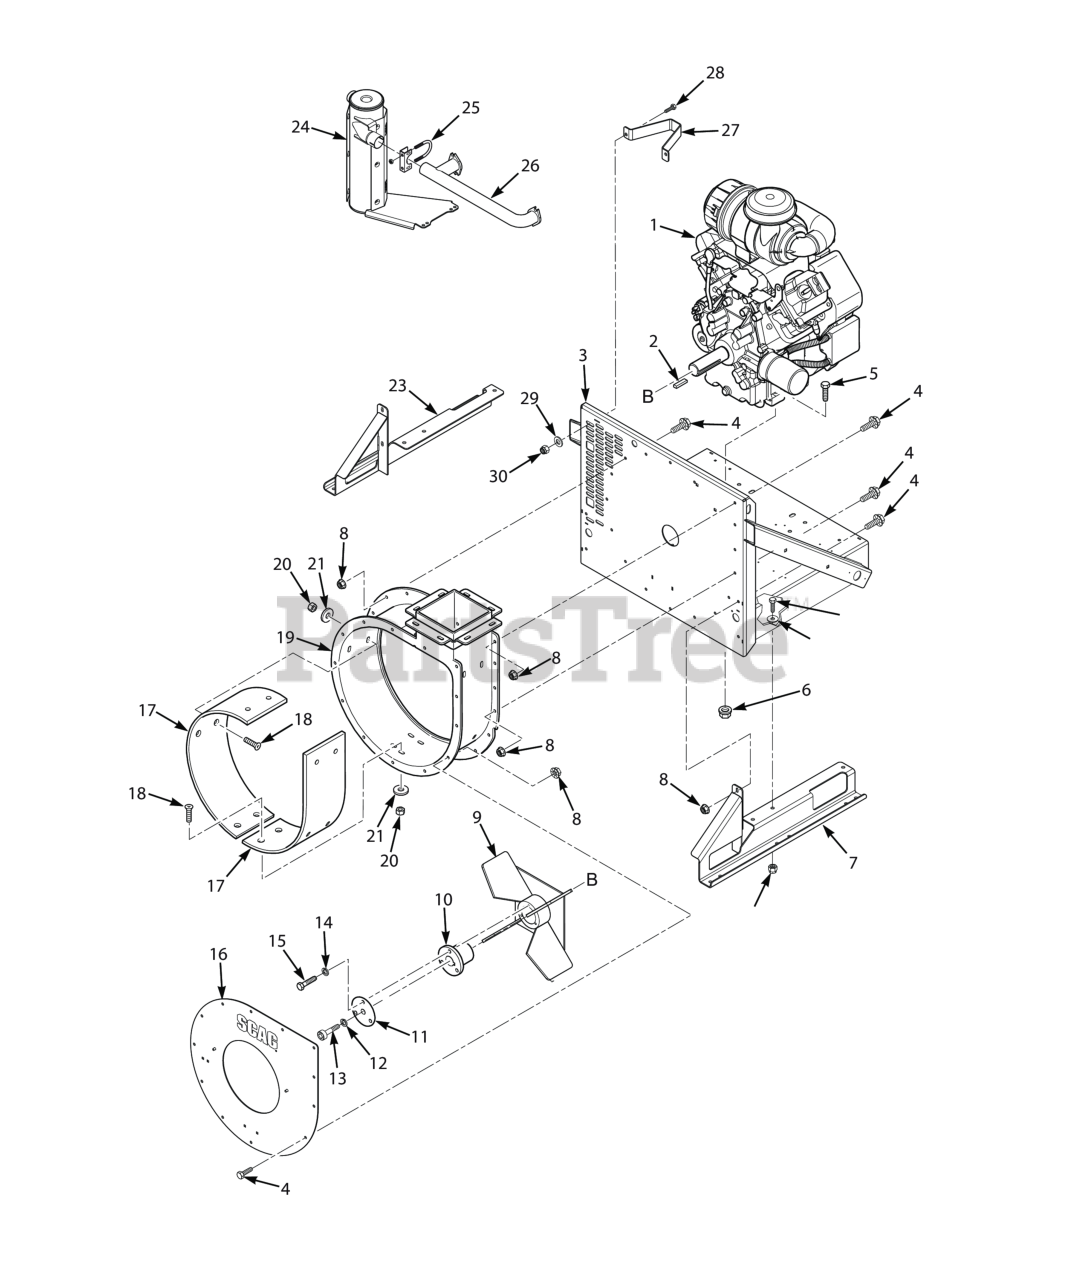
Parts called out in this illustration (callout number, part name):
1	Engine, 29HP Briggs & Stratton Vanguard
2	Key, 3/8 x 3/8 x 3-1/2"
3	Frame Weldment w / Decals
4	Bolt, Hex Head Serrated Flange 3/8-16 x 3/4"
5	Bolt, Hex Head 5/16-18 x 1-1/2" - Front
5	Bolt, Hex Head 5/16-18 x 2-1/2" (x3) (35BV & 37BV-EFI)
6	Nut, Serrated Flange 5/16-18 (Right Front Engine Mounting, Briggs and Kohler Only)
7	Mounting Bracket Weldment, RH Skid
8	NUT, 3/8-16 SERRATED FLANGE HEX HEAD
9	Impeller Weldment, TL20W
10	Hub, Tapered Locking Q2 x 1-7/16"
11	Cover Plate, Hub Taper - TL20W
12	Lockwasher, 5/8" Spring
13	Socket Head Cap Screw, 5/8-18 x 1-3/4"
14	Lockwasher, 3/8" Spring, Kawasaki FX / FS
15	Bolt, Hex Head 3/8-16 x 1-3/4" (Kohler EFI)
16	Cover, Housing - TLS20W w/Decal
17	Wearliner Kit w/ Hardware
18	Capscrew, 3/8-16 x 1-1/4"
19	Housing Weldment w / Decals
20	HEX NUT, ELASTIC STOP LOCK, 3/8-16
21	Flatwasher, 1/2 (.5/6 x .938 x .105)
22	Weldment, Exhaust Deflector - 29hp Briggs & Stratton
23	Mounting Bracket Weldment, LH Skid
24	Muffler, 29hp Briggs & Stratton
25	Clamp, Muffler (Clamp Only)
26	Exhaust Manifold, 29hp Briggs & Stratton
27	Muffler Guard
28	Bolt, Hex Head, 3/8-16 x 1 Gr. 5
29	Flatwasher, 3/8" Special (.391 x .938 x .105)
30	HEX NUT, ELASTIC STOP LOCK, 3/8-16
